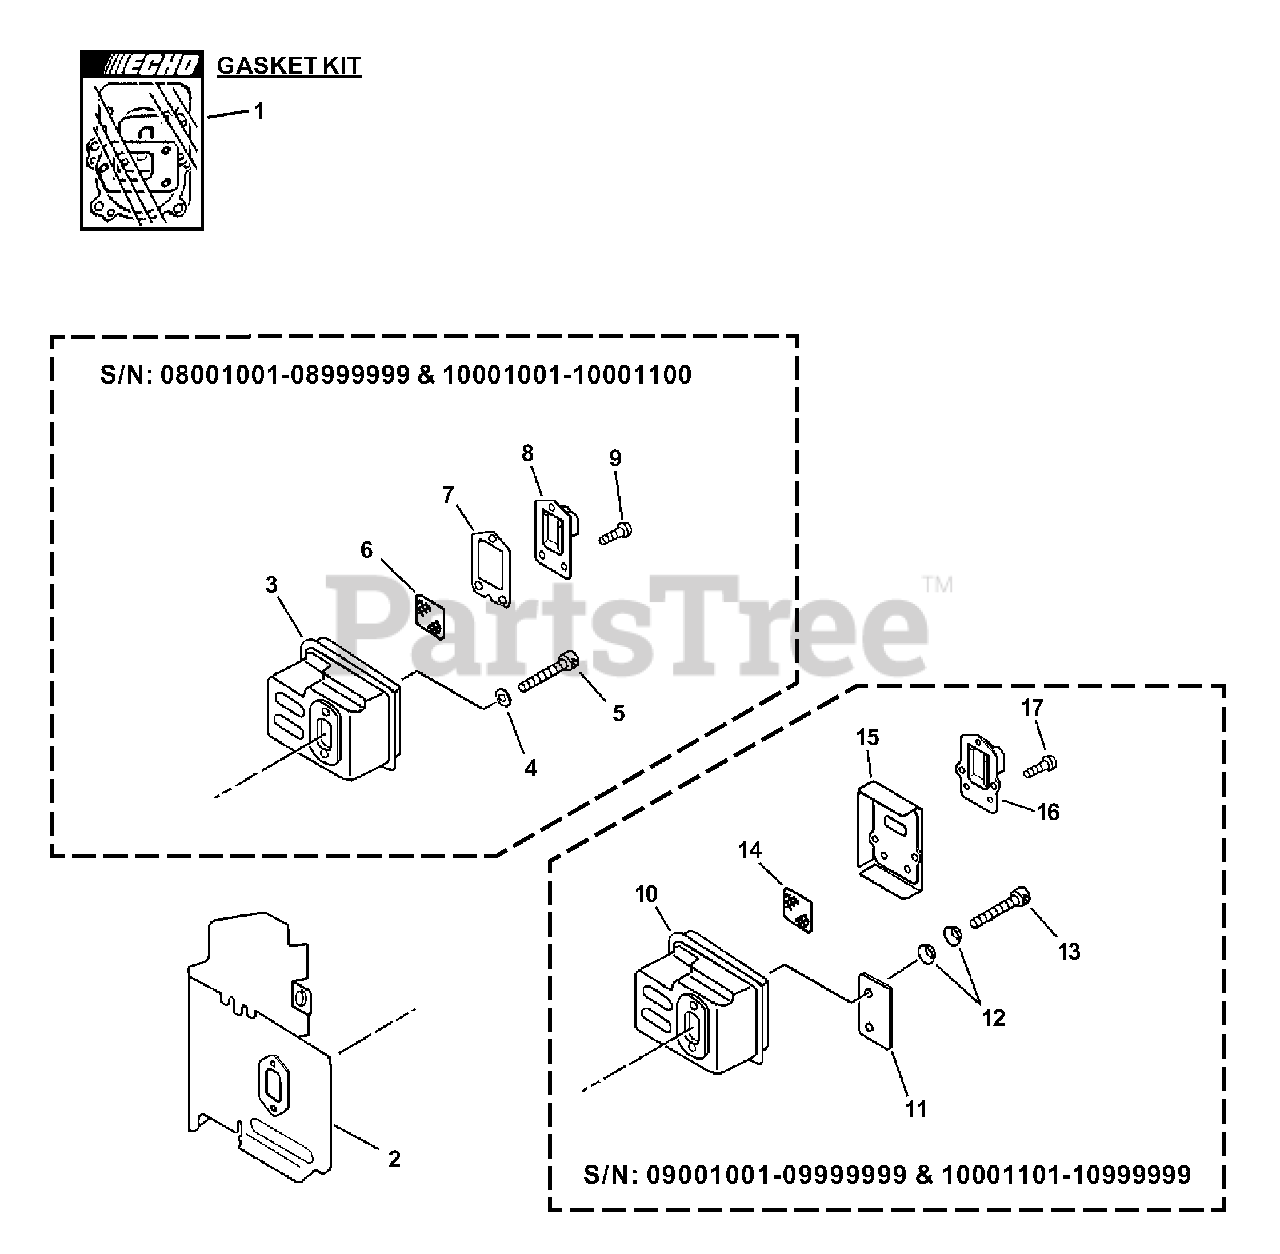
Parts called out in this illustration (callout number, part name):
1	GASKET KIT
2	SHIELD, EXHAUST
3	MUFFLER
4	WASHER - 5
5	SCREW - 5X55
6	SCREEN, SPARK ARRESTOR
7	GASKET, EXHAUST
8	GUIDE, EXHAUST
9	SCREW - 4X10
10	MUFFLER
11	PLATE
12	WASHER - CONICAL
13	SCREW - 5X55
14	SCREEN, SPARK ARRESTOR
15	GASKET, EXHAUST
16	GUIDE, EXHAUST
17	SCREW - 4X12
